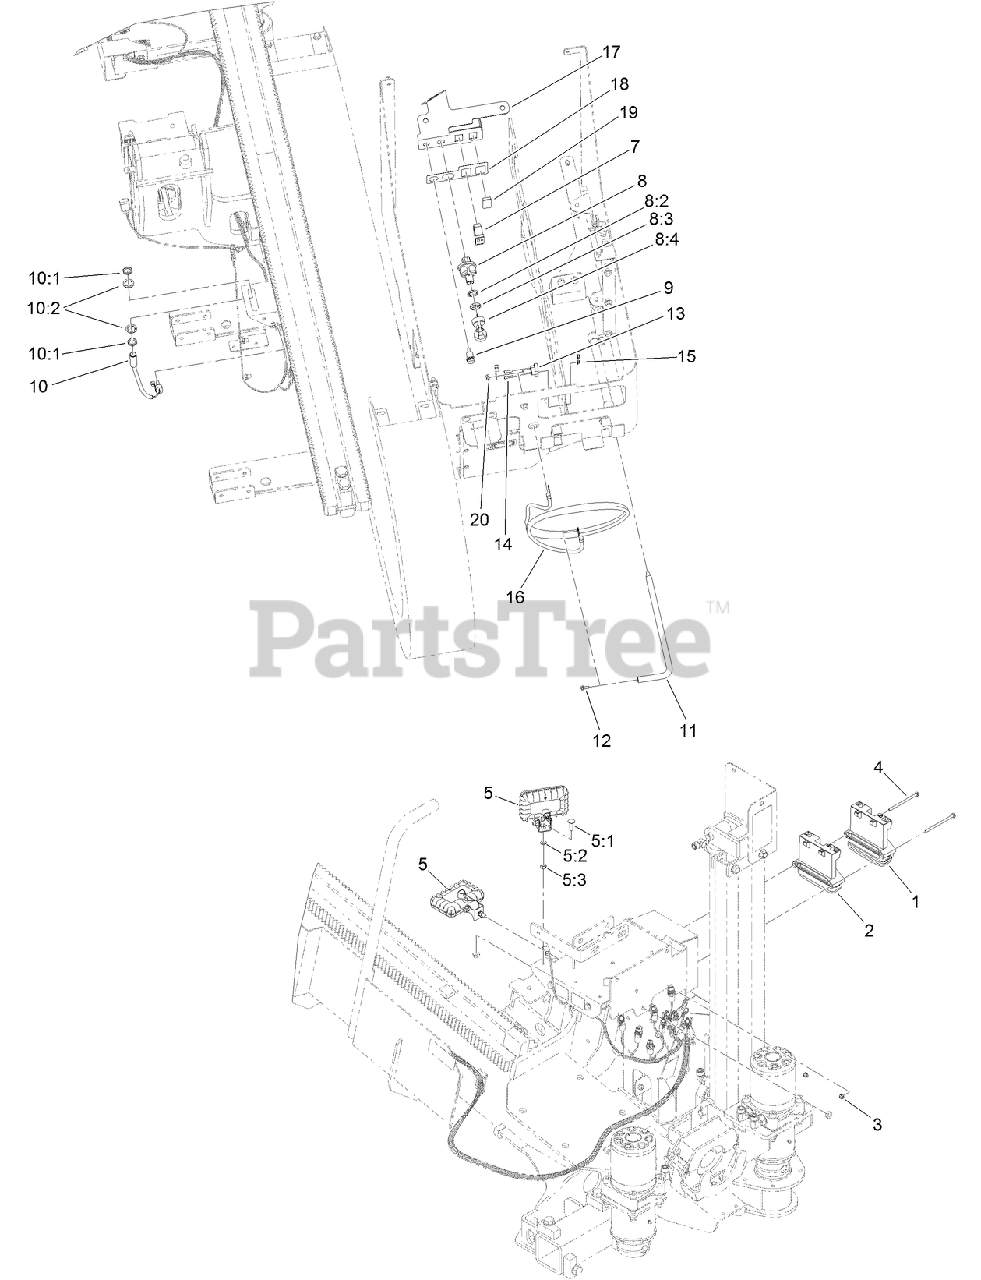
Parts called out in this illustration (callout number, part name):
1	MODULE-EXPANSION (OX024-110)
2	MODULE-EXPANSION (IOX024-120)
3	NUT-HF
4	SCREW-HH
5	LIGHT-WORK, LED
5:1	SCREW-CARR
5:2	WASHER-LOCK
5:3	NUT-HEX
7	SWITCH
8	IGNITION SWITCH ASM
8:2	NUT-HEX
8:3	NUT-FACE
8:4	SET-KEY, IGNITION
9	LAMP-INDICATOR, LED
10	PROXIMITY SWITCH ASM
10:1	NUT-HEX
10:2	WASHER-LOCK, INTERNAL TOOTH
11	BAR-STAKE, GROUND
12	SCREW-HHF
13	BLOCK-JUNCTION
14	SCREW-HSH
15	NUT-HF
16	CABLE-ALERT, STRIKE
17	PANEL-SWITCH
18	DECAL-CONTROLS
19	PLUG-HOLE
